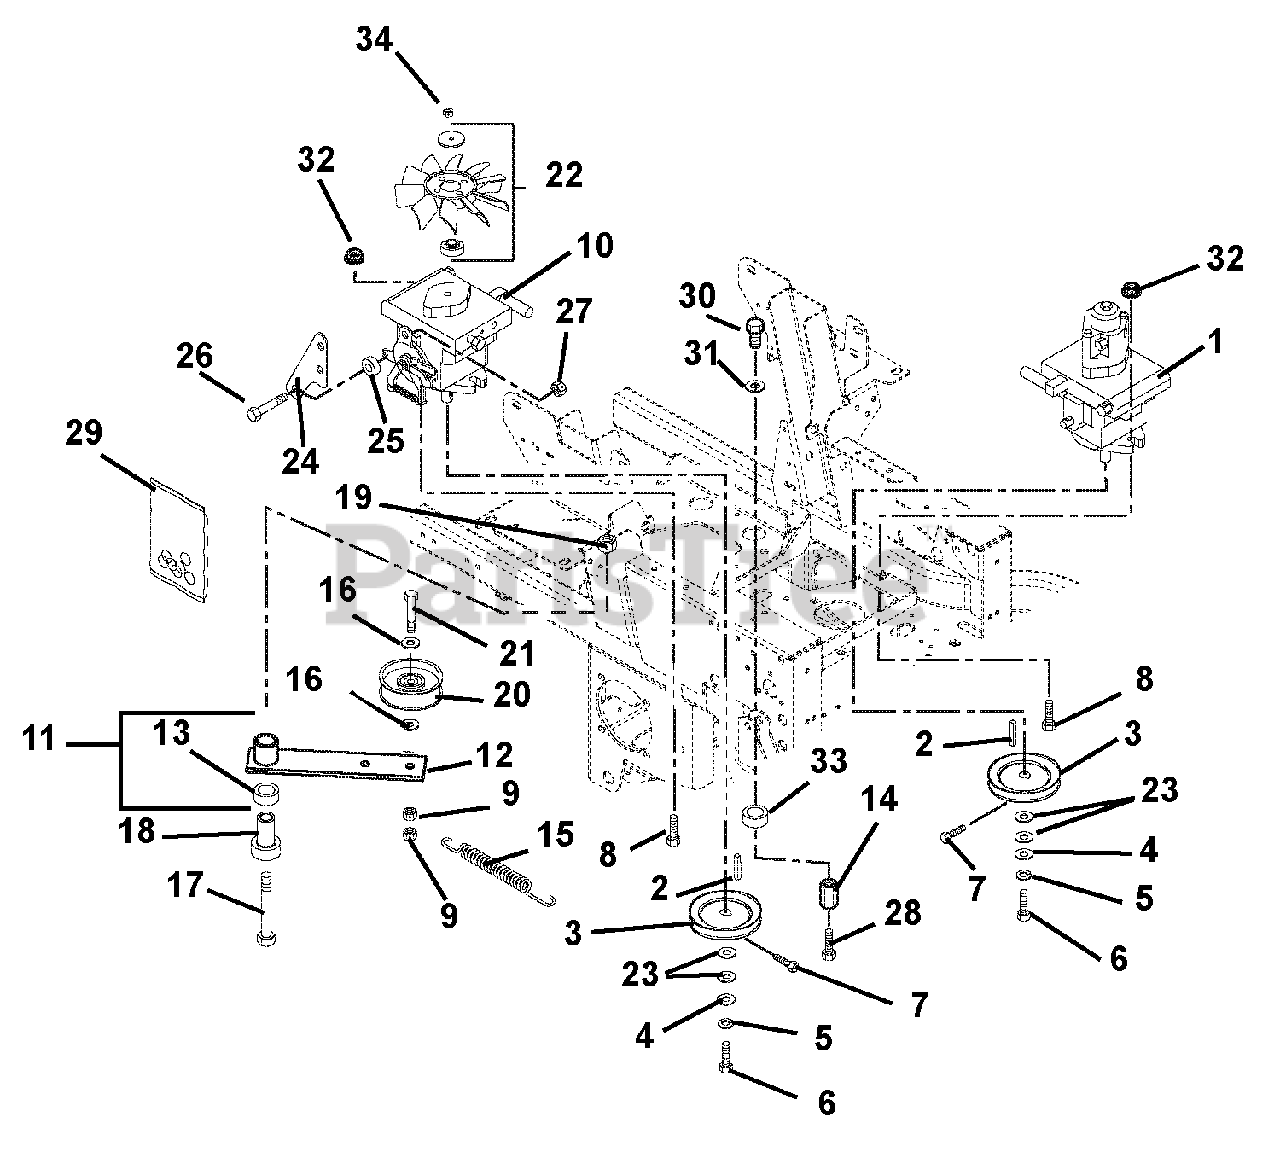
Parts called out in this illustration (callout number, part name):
1	PUMP,10CC DISP,W/AUX,W/REV RTN
2	KEY-STR 5MMX25MMX5MM
3	SHEAVE, PUMP .592 X 4.831
4	WSHR-FL-STL .281X1.000X.063
5	@WSHR-LK .25X.062 REG YWZC
6	BLT-HEX M6X1.0X12 YZ EP30
7	BLT-HEX .25-20X.50 GR5 EPOXY
8	@BLT-RDHDSQNK .44-14X1.50 G5YZ
9	@NUT-LK-TOP-FLG .38-16 YWZC
10	PUMP, BDP-10A-441 (THRU SHAFT)
11	ASSEMBLY,IDLER ARM GRD.DRIVE
12	WMT, IDLER ARM GROUND DRIVE
13	BSHG, 1.00 X 1.125 X 1.937
14	NUT COUPLING .375-16X1.75
15	SPRING, EXTENSION
16	WSHR-FL-STL .390X.75X.125 YWZC
17	@BLT-HEX .50-13X3.50 GR5 YWZC
18	BEARING, PEDESTAL
19	@NUT-LK-TOP-FLG .50-13 YWZC
20	IDLER-FLAT 4.00 X .38 NWHAMSHR
21	@BLT-HEX .38-16X2.50 GR5 YWZC
22	FAN, COOLING (W/ HUB & WASHER)
23	@WSHR-FL-STL.656X1.31X.095 YWZ
24	BRACKET, RTN/DAMPER
25	SPACER .344X1.000X.375
26	@BLT-HEX .31-18X1.25 GR5 YWZC
27	@NUT-LK-TOP-FLG .31-18 YWZC
28	BLT,HEX .38-16X1.50 GR5 EP30
29	KIT, PUMP SEAL
30	@BLT-HEX .38-16X1.00 GR5 YWZC
31	@WSHR-LK .38X.094 REG YWZC
32	NUT-LK-NYL-FLG .44-14 YWZC
33	BSHG-SLV .377X.624X.370
34	NUT-CTRLK .31-24 YWZC
